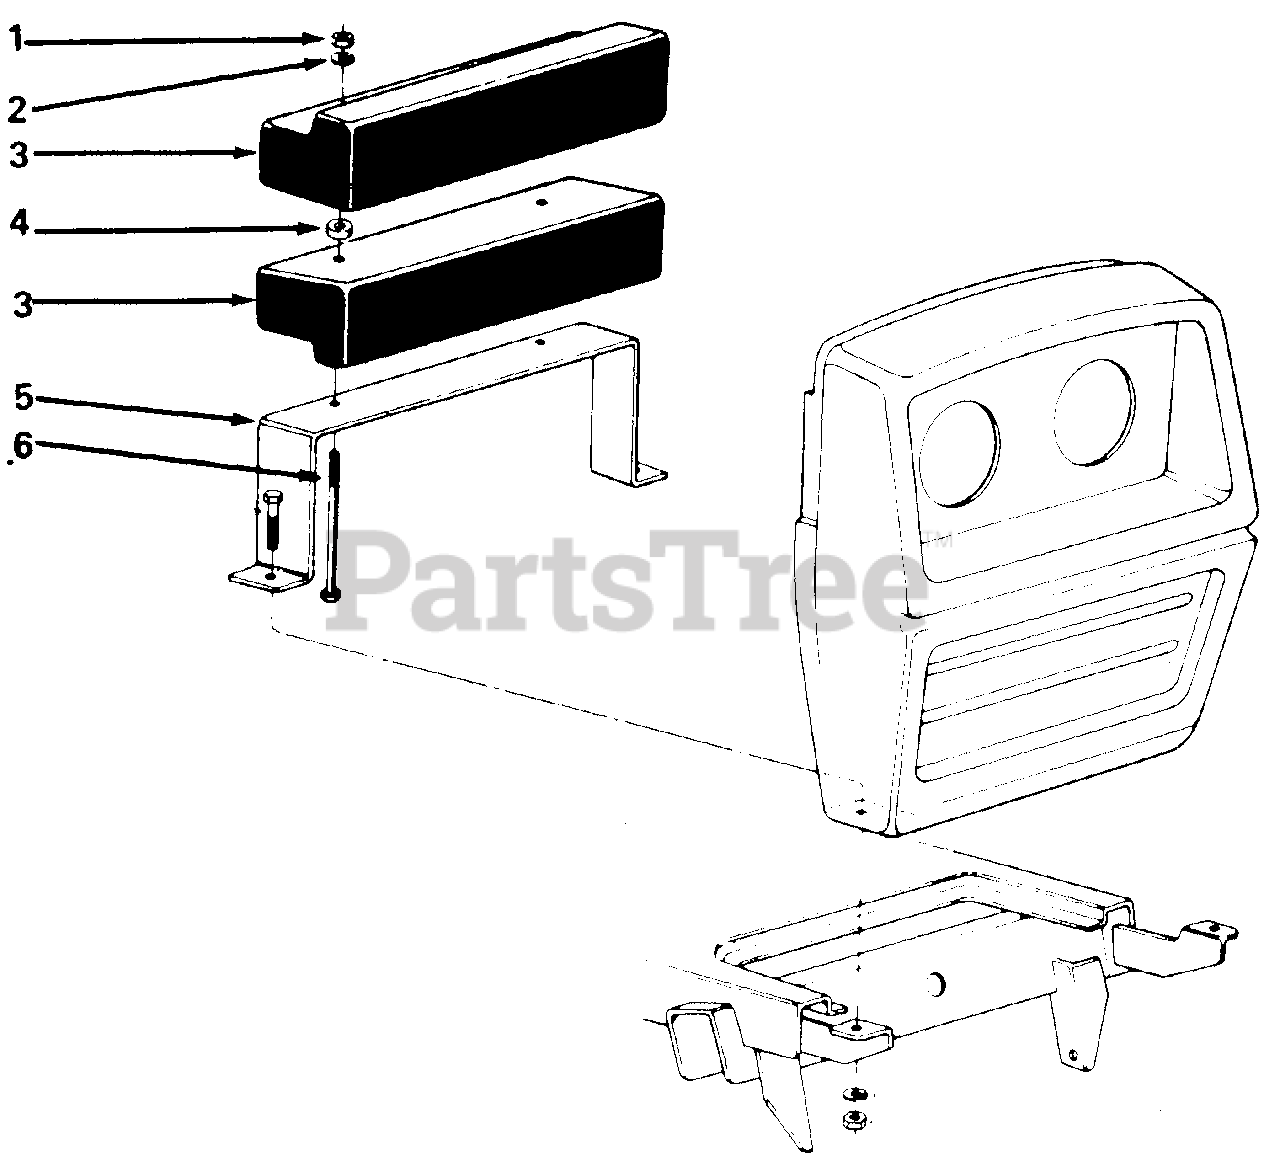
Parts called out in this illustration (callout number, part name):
1	Hex Nut 3/8-16 Thd.*
2	L.-Wash. 3/8 I.D.
3	Weight - 35 Ib.
4	Spacer
5	Front Weight Bracket
6	Hex Bolt 3/8-16 x 6.5 Lg.
